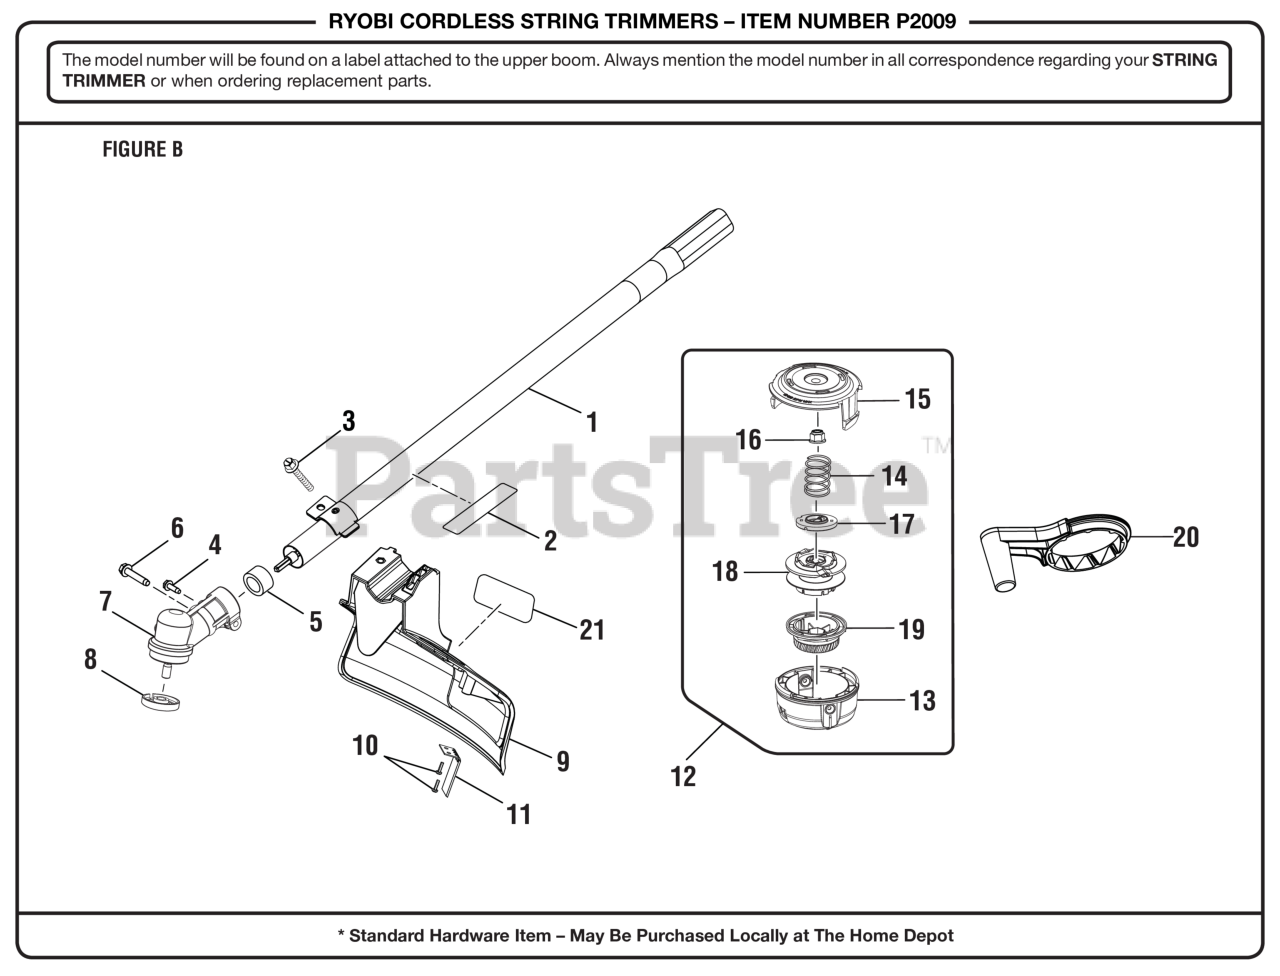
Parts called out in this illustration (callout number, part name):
1	Lower Boom Assembly
2	Lower Boom Lithium Label
3	SCREW (#1/4-20 X 1-1/4 in. HEX WASHER HD.)
4	Screw w/Washer (10-24 x 5/8 in., Hex Hd. T.F.)
6	Screw (1/4-20 x 1-1/4 in., Hex Washer Hd. S.T.)
7	Gear Case Assembly
8	FLANGED WASHER
9	Grass Deflector Assembly
10	Screw (M4 x 12 mm, Pan Hd.)
11	Line Cut-Off Blade
12	Trimmer Head Assembly (.080)
13	Lower Housing
14	Compression Spring
15	Upper Housing
16	Hex Nut (M8, Left Hand Threads)
17	String Guide
18	Spool Assembly
19	Bump Knob (Green)
20	Crank Handle Assembly
21	Logo Label (Guard)
